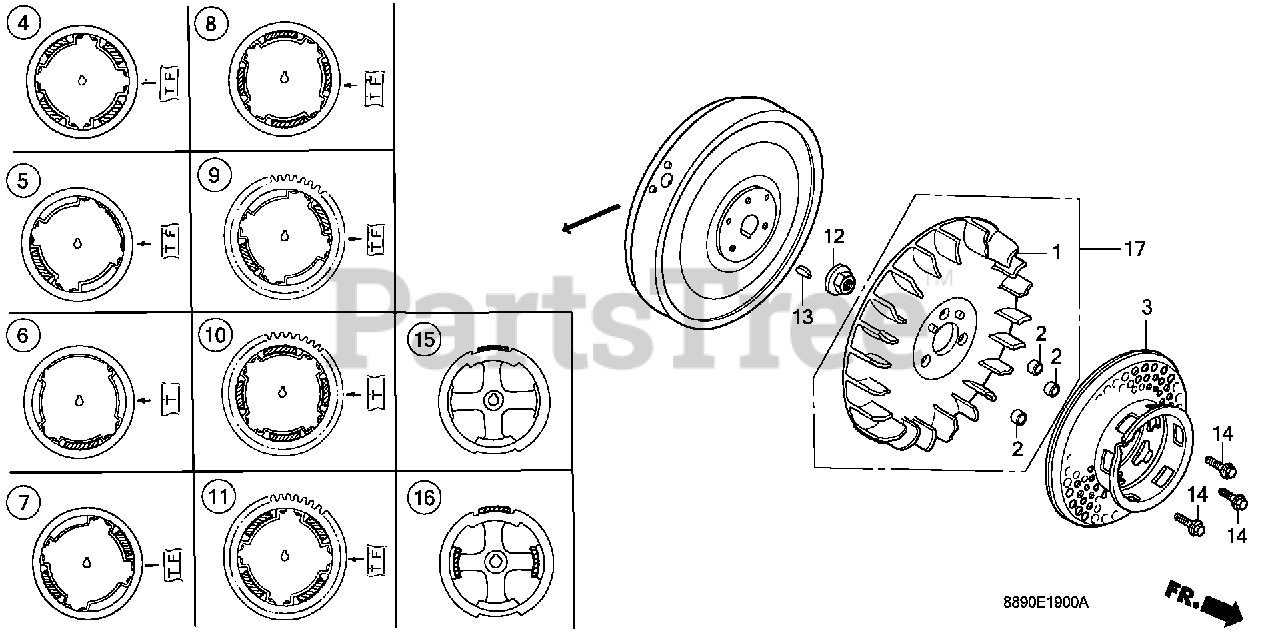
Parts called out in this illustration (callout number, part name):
1	FAN, COOLING
2	COLLAR, FAN
3	PULLEY, STARTER
3	PULLEY, STARTER (NOT AVAILABLE)
5	FLYWHEEL (NOT AVAILABLE)
10	FLYWHEEL (C.D.I.)(STARTER)
12	NUT, SPECIAL (16MM)
13	KEY, SPECIAL WOODRUFF (25X18)
14	BOLT, FLANGE (6X16)
